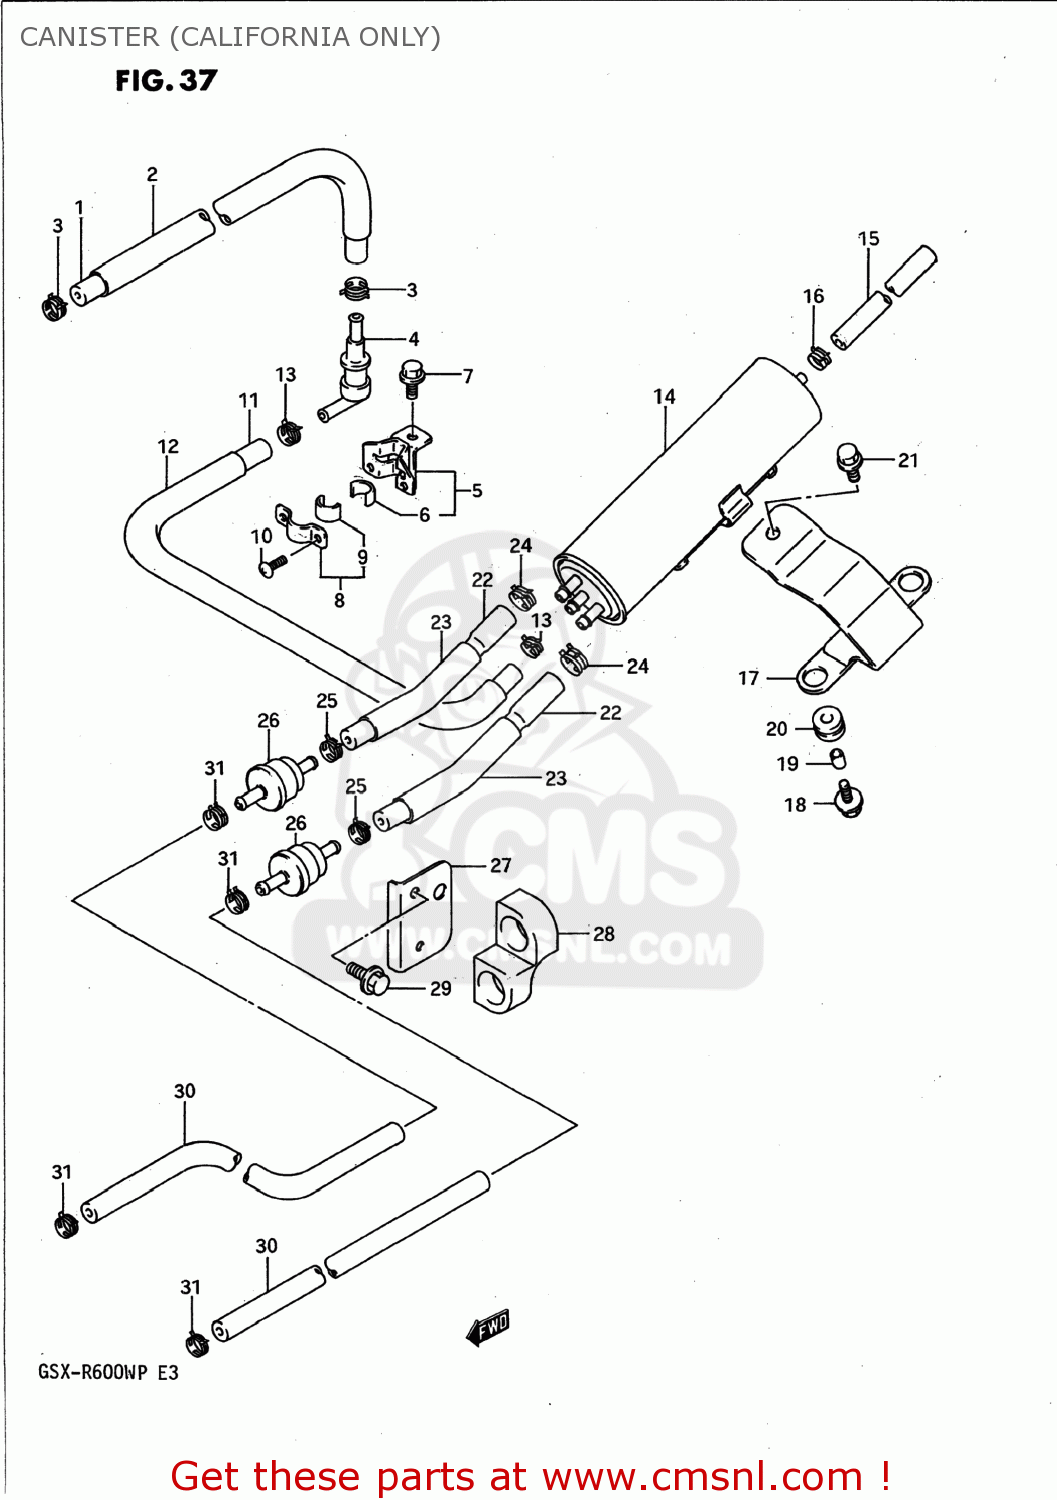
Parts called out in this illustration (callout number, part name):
1	HOSE
2	PROTECTOR,FUEL HOSE
3	(CA) CLIP
4	VALVE,FUEL TANK BREATHER
5	BRACKET,BREATHER VALVE
6	CUSHION
7	BOLT 6X12
8	PLATE,FUEL TANK BREATHER NO.2
9	CUSHION
10	SCREW
11	HOSE
12	PROTECTOR,EVAPORATOR HOSE,LEFT
13	(CA) CLIP
14	CANISTER ASSEMBLY,CHARCOAL
15	HOSE (7X12X150)
16	CLAMP
17	BRACKET,CANISTER
18	BOLT
19	SPACER
20	CUSHION
21	BOLT
22	HOSE
23	PROTECTOR,EVAPORATOR HOSE,N
24	CLAMP
25	(CA) CLIP
26	VALVE,CANISTER PURGE
27	BRACKET,CANISTER PURGE VALVE
28	(CA) CUSHION,CANISTER P VA
29	BOLT 6X12
30	HOSE (5.4X11.4X600)
31	(CA) CLIP
